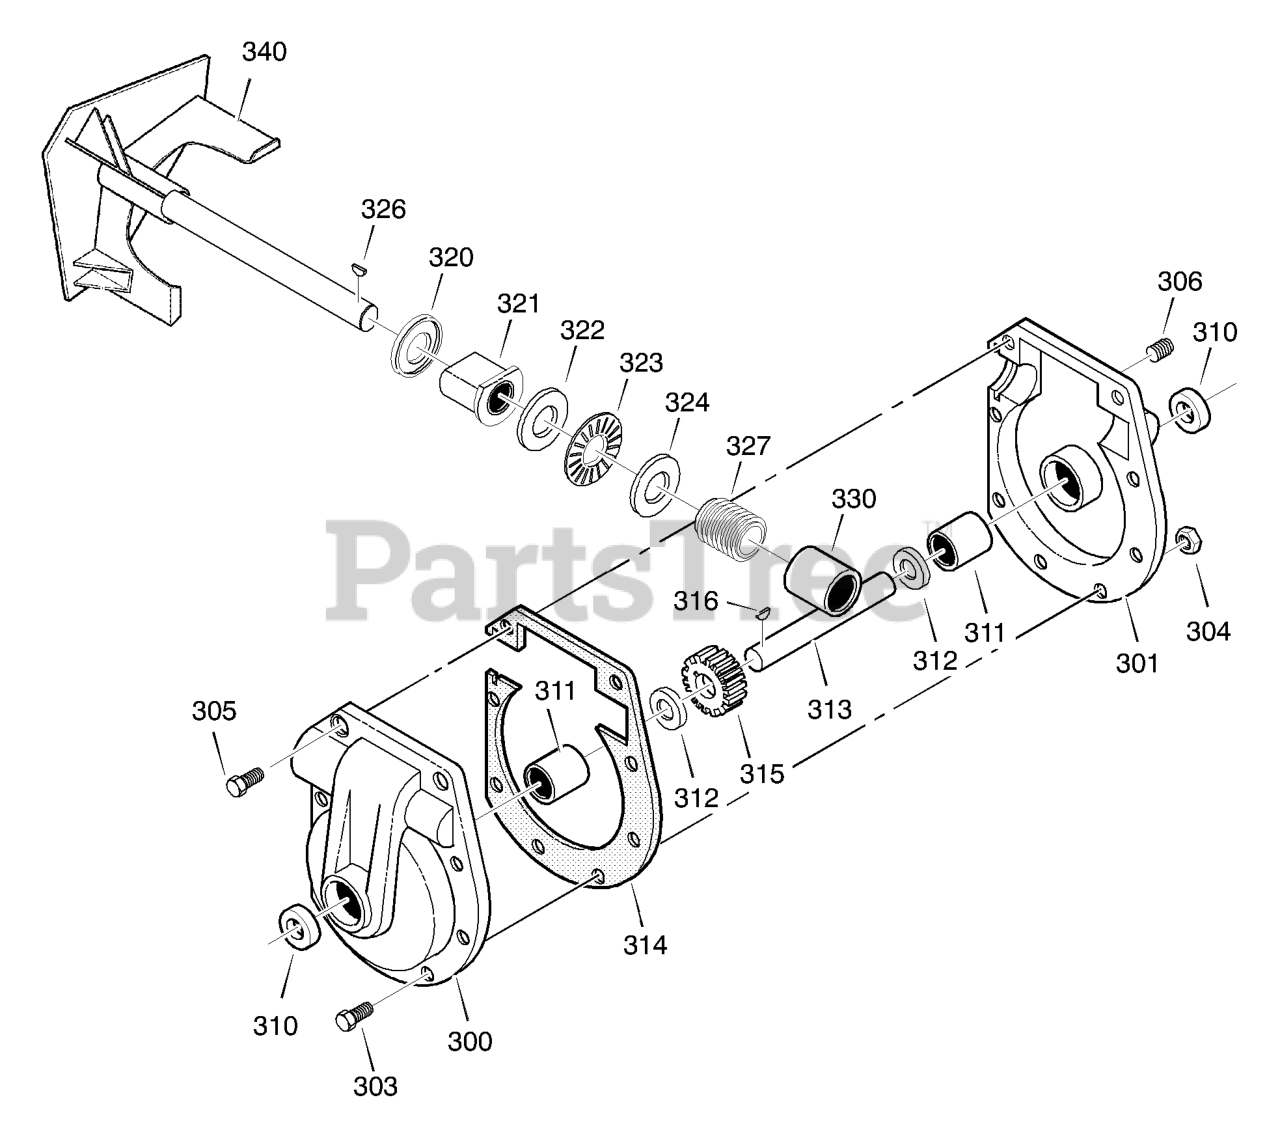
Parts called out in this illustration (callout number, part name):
300	CASE, GEAR, RH
301	CASE, GEAR, LH
303	SCREW, 5/16-24 x 1.00
304	NUT, 5/16-24
305	SCREW, 5/16-24 x 1.50
306	PLUG, PIPE 0.25-18
310	SEAL, OIL
311	BEARING, SLEEVE
312	WASHER, FLAT
313	SHAFT, AUGER OUTPUT
314	GASKET, GEAR BOX
315	WORM GEAR
316	KEY, WOODRUFF #91
320	RING, QUAD 0.924 ID
321	BEARING, FLANGE
322	WASHER, FLAT
323	BEARING, ROLLER
324	WASHER, FLAT
330	BEARING, SLEEVE
340	IMPELLER
